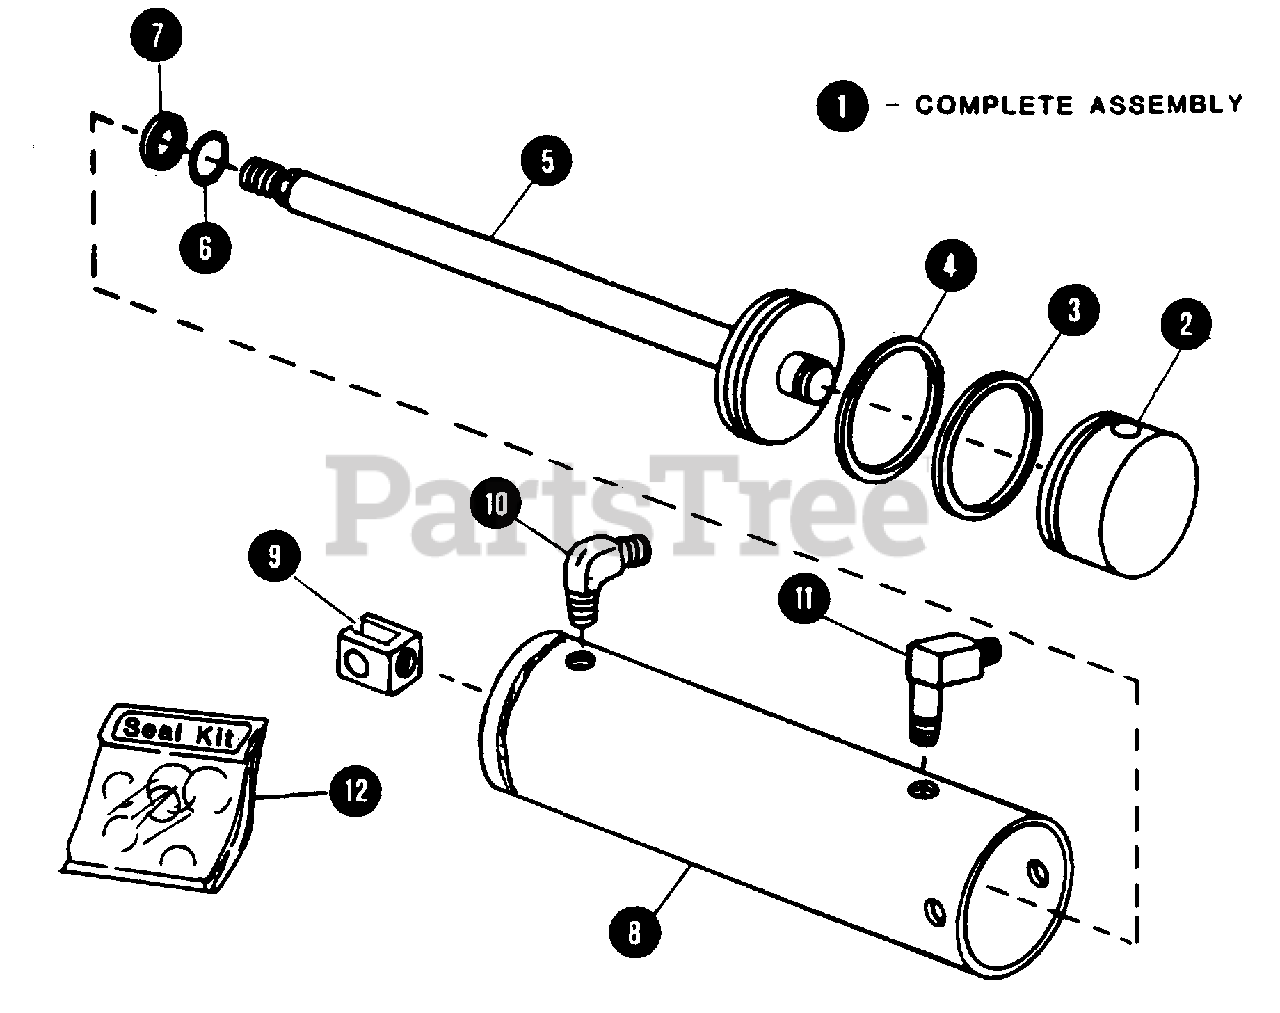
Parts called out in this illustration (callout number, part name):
1	CYLINDER, REAR LIFT ASSEMBLY
2	HEAD, CYLINDER
3	PACKING, CYLINDER HEAD
4	SEAL, PISTON
5	PISTON-ROD ASSEMBLY
6	O-RING, PISTON ROD
7	RING, PISTON ROD BACK-UP
8	TUBE, CYLINDER
9	FITTING, PISTON ROD END
10	ELBOW, 1/4-18 NPTF x 9/16-18 NF - 90°.
11	ELBOW, 1/4-18 NPTF x 9/16-18 - 90° (LONG)
12	KIT, SEAL REPLACEMENT
